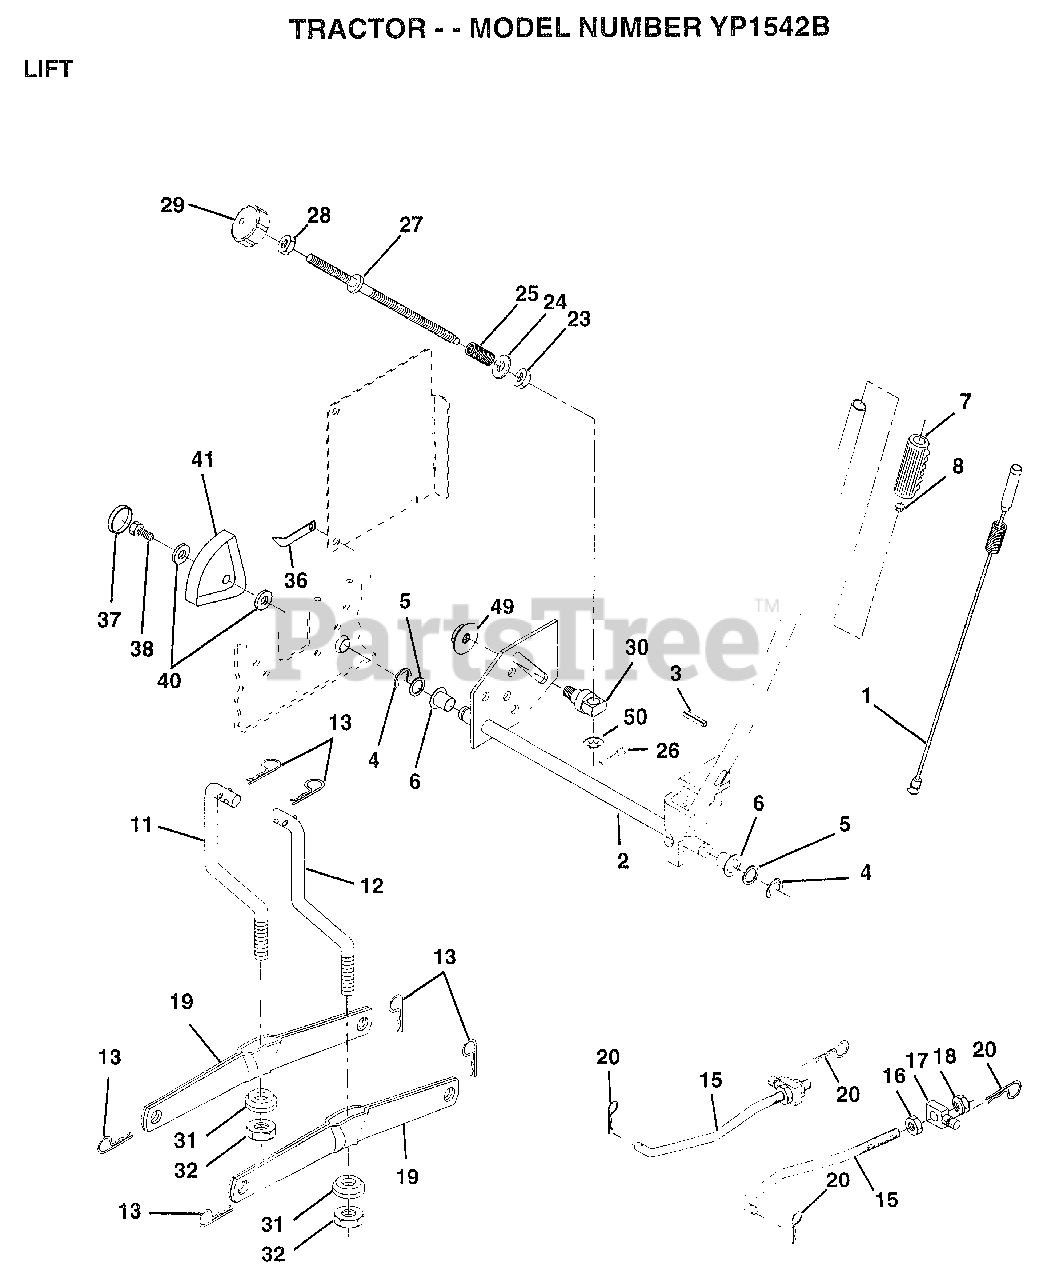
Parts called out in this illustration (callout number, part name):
1	WIRE ASM W.SPRING
2	"SHAFT ASM LIFT,RH"
3	PIN-GROOVE LT
5	WASHER
6	NYLON BEARING
7	GRIP HANDLE
15	LINK.FRONT
16	NUT
17	TRUNION
18	NUT.LK.W/WSH.1/2.
19	ARM SUSP REAR
20	RETAINER SPRING
23	NUT T
24	WASHER
25	SPRING T
28	NUT
29	KNOB INF 3/8-16
30	TRUNNION
31	BEARING PVT LH
32	NUT.CROWNLOCK.3/8
36	POINTER-INDICAT
37	"PLUG,HOLE"
38	SCREW
40	WASHER
41	HEIGHT INDICATOR
49	NUT.HXFLG.LOCK.
